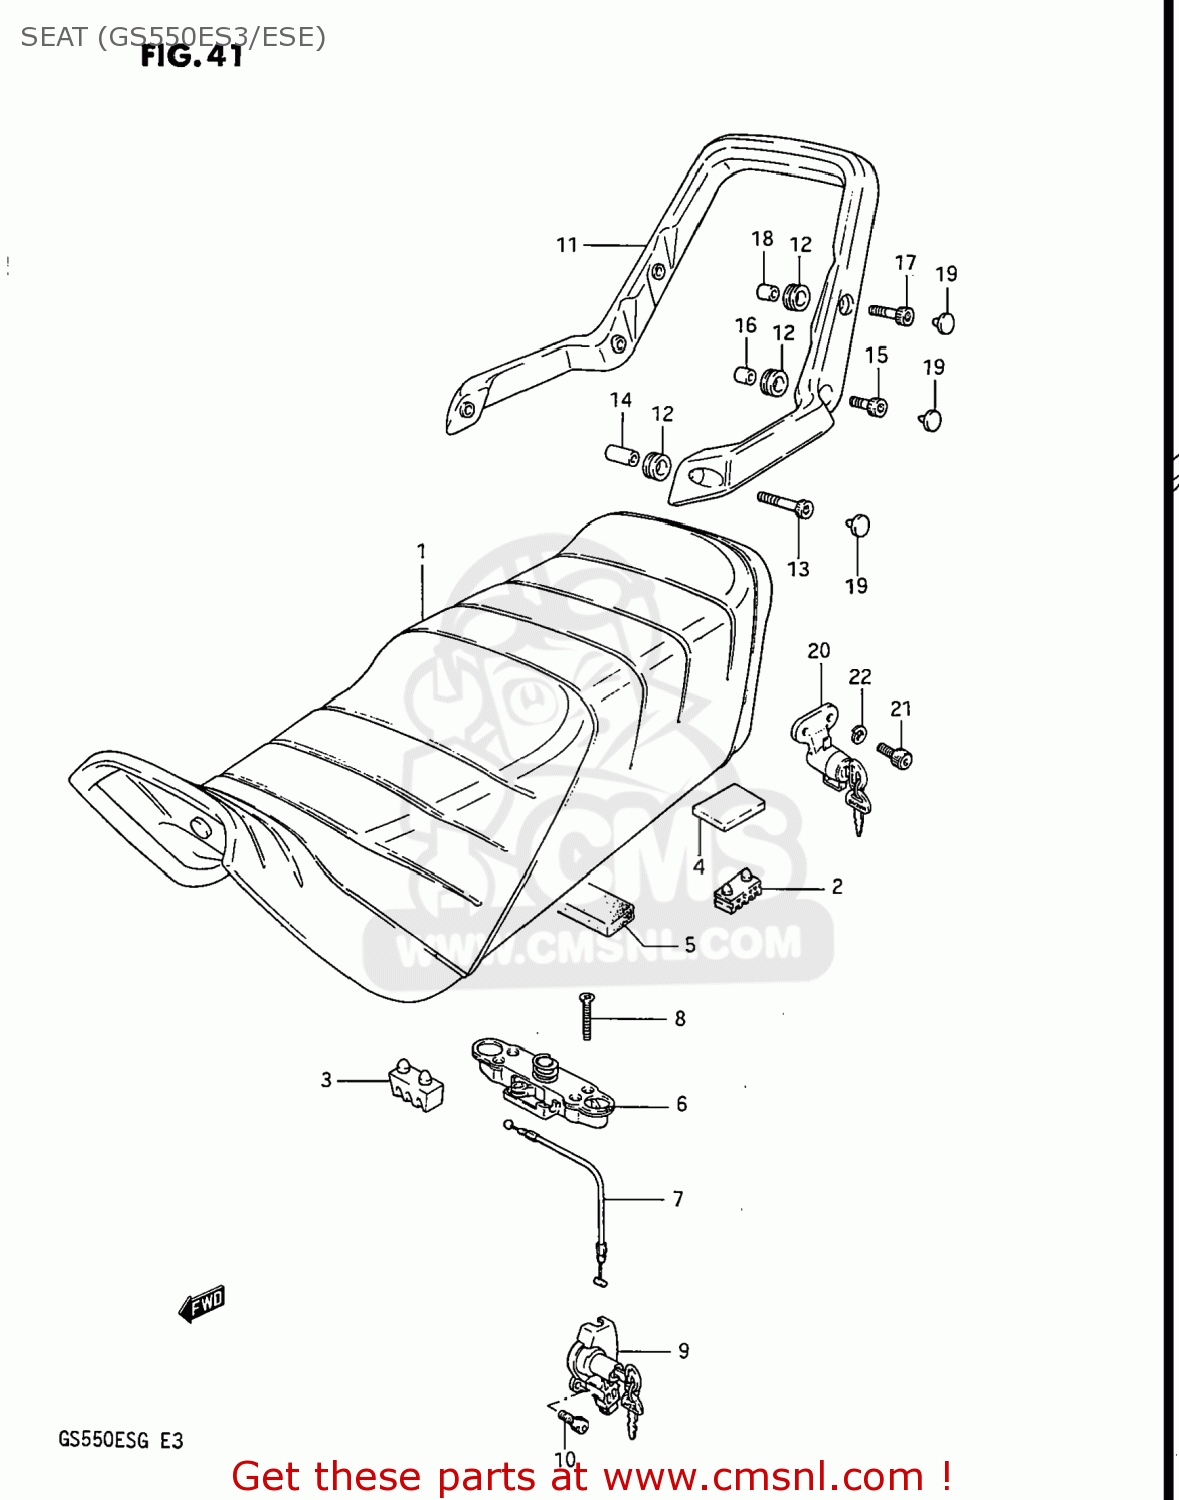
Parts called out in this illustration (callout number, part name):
1	SEAT ASSEMBLY
2	CUSHION,SEAT(40X20X15)
3	CUSHION,SUPPORT(50X25X32)
4	CUSHION,STRIKER
5	CUSHION(30X60X10)
6	LOCK ASSEMBLY,SEAT STRIKER
7	CABLE,SEAT LOCK
8	SCREW
9	LOCK ASSEMBLY,SEAT & HELMET
10	BOLT
11	HANDLE,PILLION RIDER
12	GROMMET,PILION RIDER HANDLE
13	BOLT
14	SPACER,PILLION RIDER HOLDER
15	BOLT
16	SPACER,PILLION RIDER HOLDER
17	BOLT
18	SPACER,PILLION RIDER HOLDER
19	CAP(OD:10)
20	LOCK ASSEMBLY,HELMET
21	BOLT
22	LOCK WASHER
